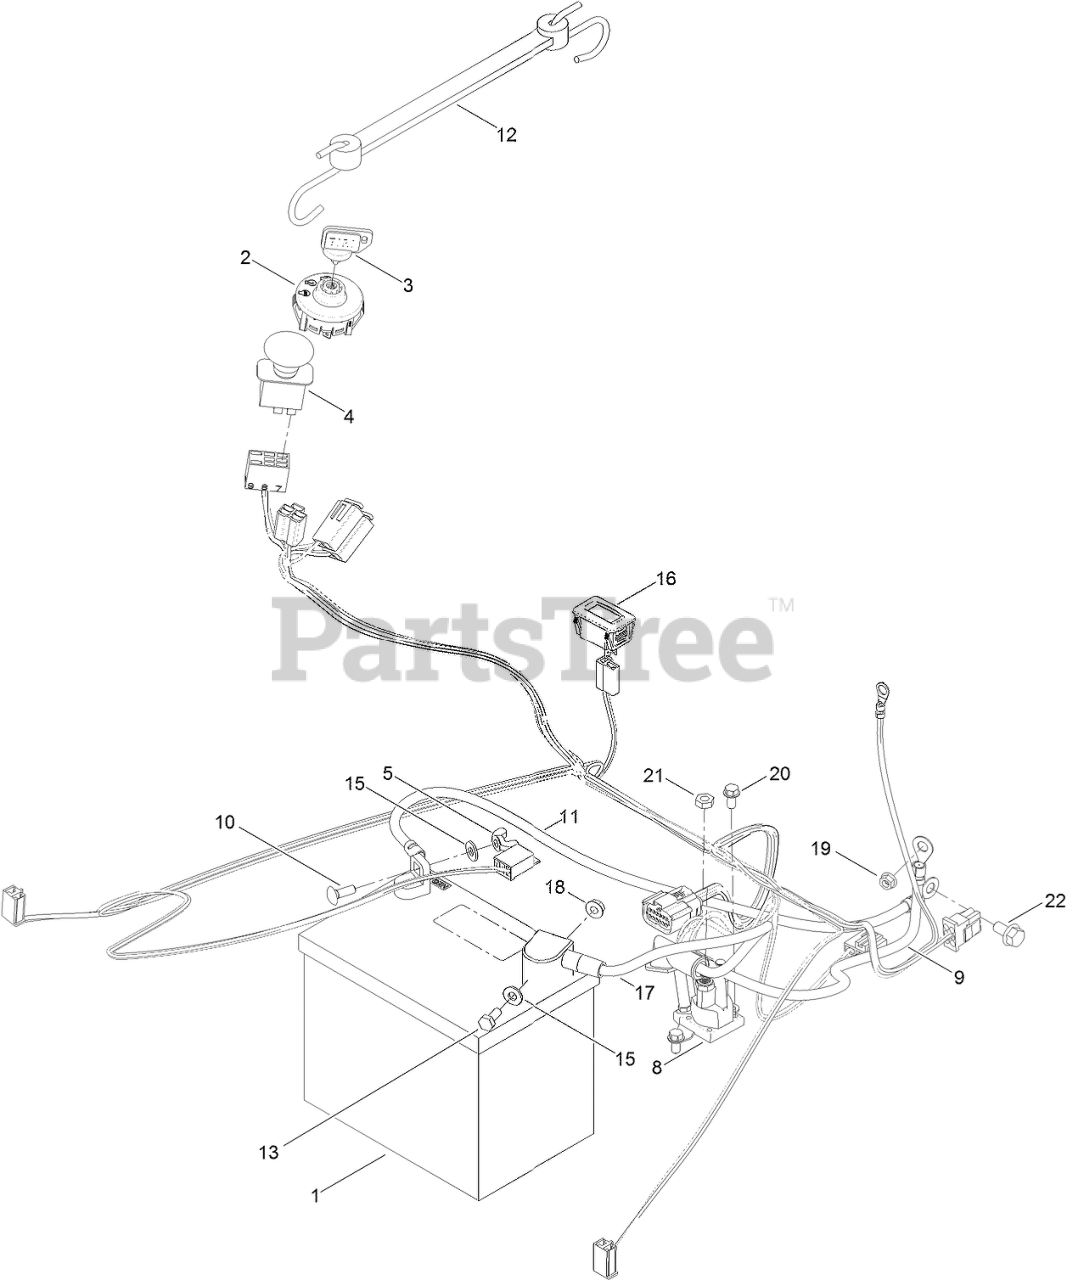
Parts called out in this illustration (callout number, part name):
1	BATTERY
2	SWITCH-IGNITION
3	KEY-IGNITION
4	SWITCH-PTO, ON-ON-(ON)
5	NUT-WING
8	SOLENOID
9	CABLE-BATTERY, POSITIVE
10	BOLT-CARR
11	CABLE-BATTERY, BLACK
12	HOLDDOWN-BATTERY
13	SCREW-HH
15	WASHER-FLAT
16	HOURMETER
17	CABLE-BATTERY, RED
18	NUT-HF
19	NUT-HF
20	SCREW-HWH
21	NUT-JAM
22	SCREW-HHF
